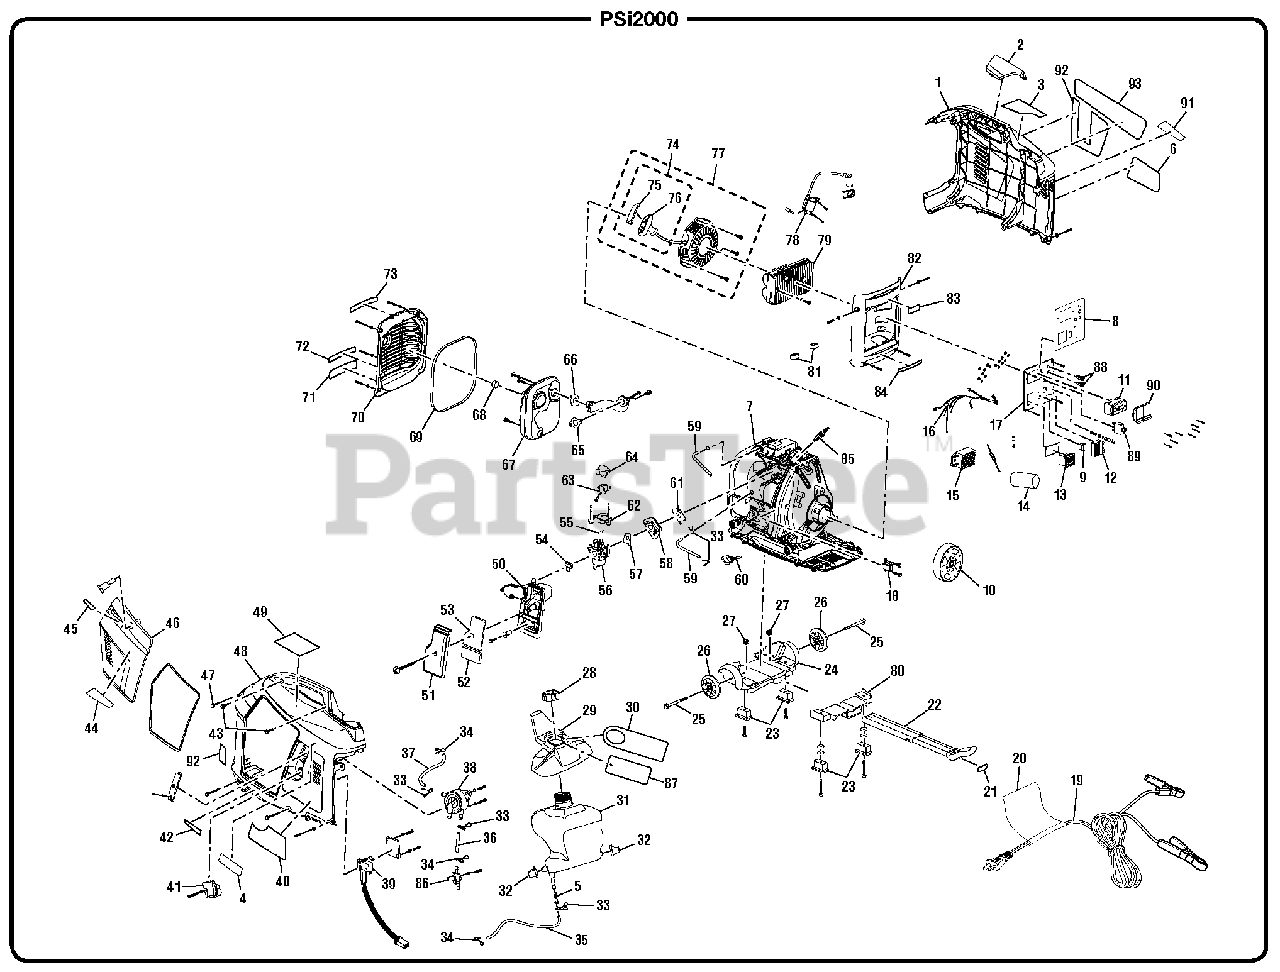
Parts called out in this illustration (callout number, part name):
1	Right Housing
2	Spark Plug Access Cover
3	Danger / E85 Label
4	Fire Danger Label
5	Fuel Filter
6	Features Label
8	Control Panel Label
9	Auto Idle Switch
10	Stator Assembly
11	AC Receptacle (120 Volt)
12	Ignition Module
13	DC Receptacle
14	Heat Shrink Tube
15	Bridge Rectifier
16	Wiring Harness (Internal)
17	Control Panel
18	Pick-Up Coil
19	Battery Charging Cable
20	Cord Label
21	Handle Release Label
22	Handle Assembly
23	Rubber Foot
24	Rear Handle and Wheel Bracket
25	Wheel Mounting Bolt
27	Hex Nut (Wheel Mounting)
28	Fuel Cap Assembly
29	Fuel Overspill Guard
30	Hangtag (Warning)
31	Fuel Tank
32	Fuel Tank Support
33	Clamp (D9 x 1.2 mm)
34	Clamp (D7 x 0.8 mm)
35	Fuel Line (D4 x D8 x 260 mm)
36	Fuel Line (D4 x D8 x 130 mm)
37	Fuel Line (D4 x D8 x 170 mm)
38	Fuel Pump
39	Engine Shut Off Switch
40	Quick Start Label
41	Switch Handle
42	Lubricant Label
43	Bolt (M6 x 30 mm)
44	Logo Label (Left)
45	Choke Label
46	Maintenance Cover
47	Bolt (M6 x 100 mm)
48	Left Housing
49	CPSC Label
50	Air Filter Back
51	Air Filter Cover
52	Air Filter (Lower)
53	Air Filter (Upper)
54	Intake Gasket
55	Governor Damping Spring
56	Carburetor Assembly
57	Carburetor Gasket
58	Heat Dam Insulator
59	Pulse Line (D7 x D11 x 160 mm)
61	Insulator Gasket
62	Governor Bottom Cover
64	Governor Top Cover
65	Manifold Gasket
66	Muffler Gasket
68	Spark Arrestor
69	Muffler Cover Seal
70	Muffler Cover
71	Data Label
72	Combustion Label
73	Hot Surface Label
74	Rope Handle Assembly (Inc. Key Nos. 75-76)
75	Handle Cover (Rope)
76	Rope Handle
77	Recoil Starter Assembly (Inc. Key Nos. 75-76)
78	Ignition Coil
79	Inverter Module
80	Foot Brace (Front Handle)
81	Inverter Module Support
82	Control Panel Holder
83	Logo Label (Small)
84	Ground Warning Label
85	Spark Plug
86	Fuel Shut Off Valve
87	Hangtag (Instructions)
88	Parallel Plug
89	Circuit Breaker (20 Amp)
90	Receptacle Cover
91	Logo Label (Right)
92	Performance Label
93	Check Oil Label
